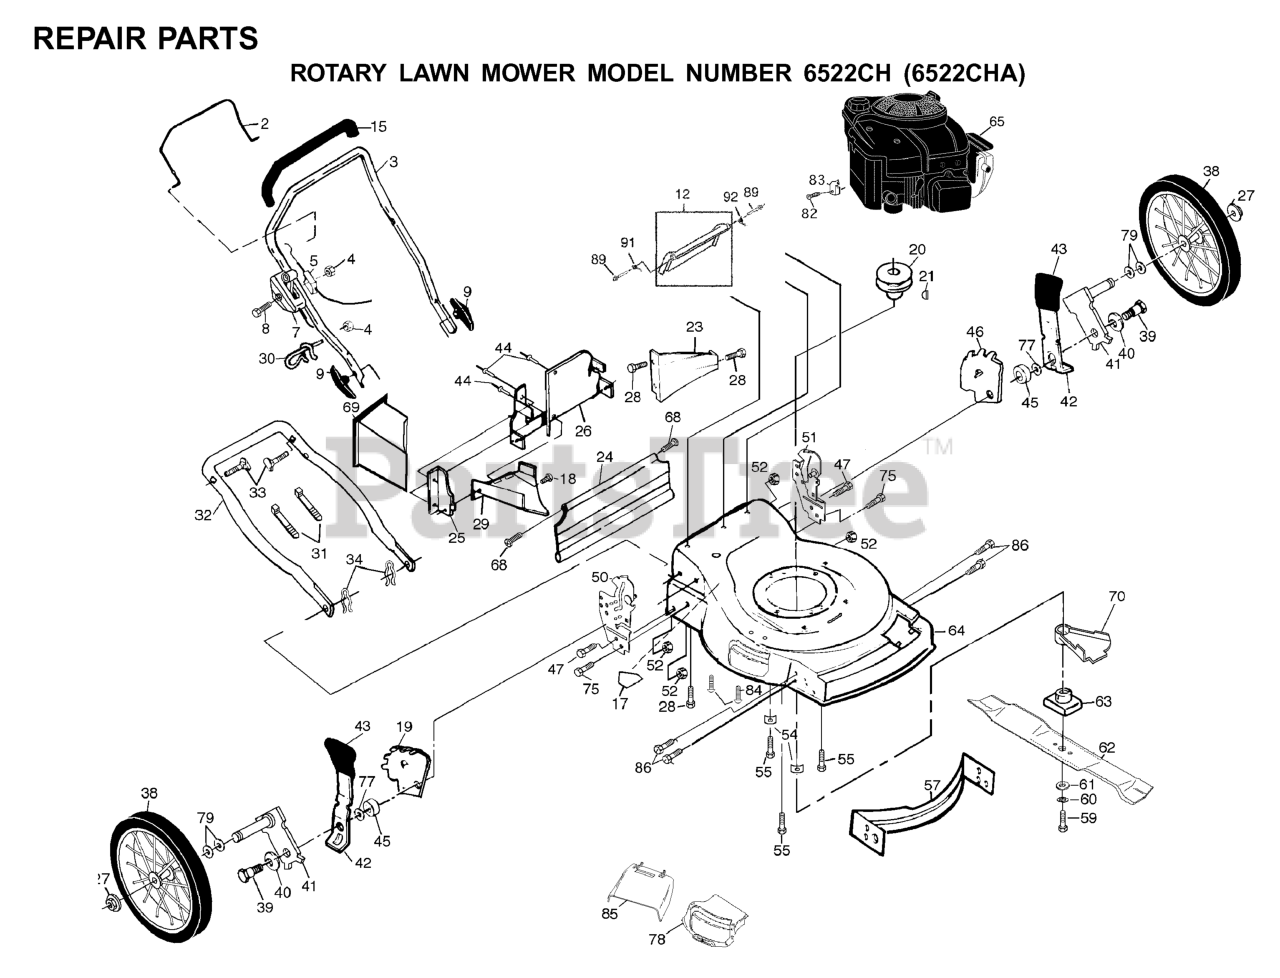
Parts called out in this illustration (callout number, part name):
3	HANDLE, UPPER DLX COMF. (GRIP)
4	NUT
5	CABLE.MZR.51.RT.SP./PU.
7	THROTTLE CONTROL
8	SCREW 1/4-20 X 2.12
9	HANDLE KNOB
12	REAR DOOR KIT
15	GRIP.HANDLE.FOAM
17	DECAL HYT
18	SCREW.HXTAP.10-24
19	WHEEL ADJ BRKT
20	ENGINE.PULLEY.FWG
21	HI PRO KEY PM WSL
23	REAR BAFFLE
24	REAR SKIRT
25	SIDE BAFFLE
26	BACK PLATE
27	HEX FLANGE LOCKNT
29	DISCHARGE BAFFLE
30	ROPE GUIDE
31	TIE GUIDE
32	LOWER HANDLE
33	HANDLE BOLT
34	HAIRPIN COTTER
39	BOLT
44	RIVET BLIND
45	RP SPACER HT ADJ
46	WHEEL ADJ BRKT
47	SELF-TAPPING SCREW 5/16-18X3/4
52	LOCKNUT PM
54	WASHER.ENGINE.BZP
55	BOLT 3/8-16X1-1/8
59	SCREW, HEX HD 3/8-24 X 1-3/8
60	LOCKWASHER
61	WASHER,HARDEN
63	BLADE ADAPTOR
68	HINGE SCREW
69	PLUG.MULCH.22RD
70	DEBRIS SHIELD
77	WASHER.FLAT.1/2
79	WAVE WASHER
82	SCREW.HEX.HEAD.WASHER.10-16
83	WASHER
84	NUT
86	SCREW 1/4X20
89	DOOR BOLT
91	DOOR SPRING RH
92	DOOR SPRING LH
